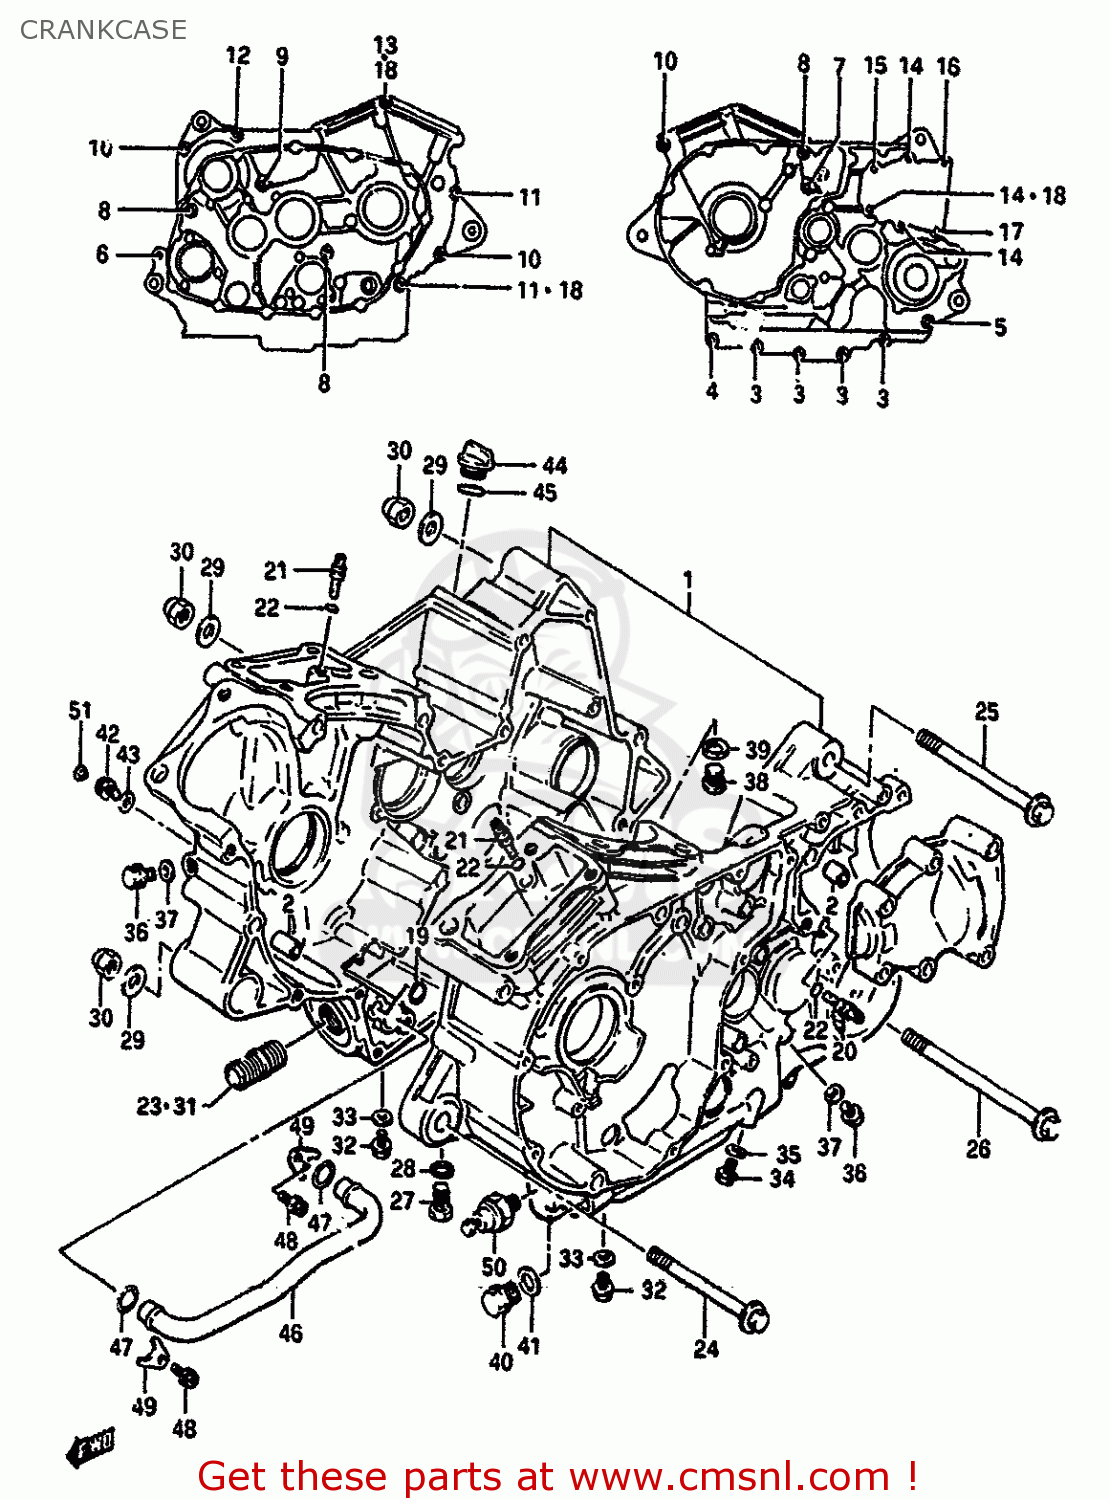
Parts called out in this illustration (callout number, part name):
1	CRANKCASE SET
2	PIN (11X20)(SUS)
3	BOLT
4	BOLT
5	BOLT 8X55
6	BOLT
7	BOLT 8X75
8	BOLT (8X95)
9	BOLT(8X120)
10	BOLT(8X95)
11	BOLT(8X105)
12	BOLT(8X120)
13	BOLT(8X160)
14	BOLT (8X40)
15	BOLT
16	BOLT(8X55)
17	BOLT(8X65)
18	GASKET 8.2X14X1 (NAS)
19	O-RING
20	JET,OIL GALLERY
21	JET,AIR(14)
22	O RING(D:1.2,ID:4)
23	UNION,OIL STAND
24	BOLT(10X125)
25	BOLT
26	BOLT(10X150)
27	BOLT
28	GASKET(12.1X16.2X3.7) (NAS)
29	WASHER 10MM
30	NUT
31	UNION,OIL STAND
32	BOLT 8X12
33	GASKET(8.2X14X1).6 (NAS)
34	PLUG(10X12)
35	GASKET(10X14X3.6) (NAS)
36	BOLT
37	GASKET(5.8X13X1.2) (NAS)
38	PLUG
39	GASKET(16X22X2) (NAS)
40	PLUG (14X12)
41	GASKET(14X19.2X2) (NAS)
42	BOLT
43	GASKET(8.2X14X1).6 (NAS)
44	PLUG
45	O RING(D:3.1,ID:16.8)
46	PIPE,OIL GALLERY
47	O RING(D:3.1,ID:14.8)
48	BOLT
49	CLAMP,OIL PIPE
50	SWITCH ASSEMBLY
51	CAP(OD:11)
